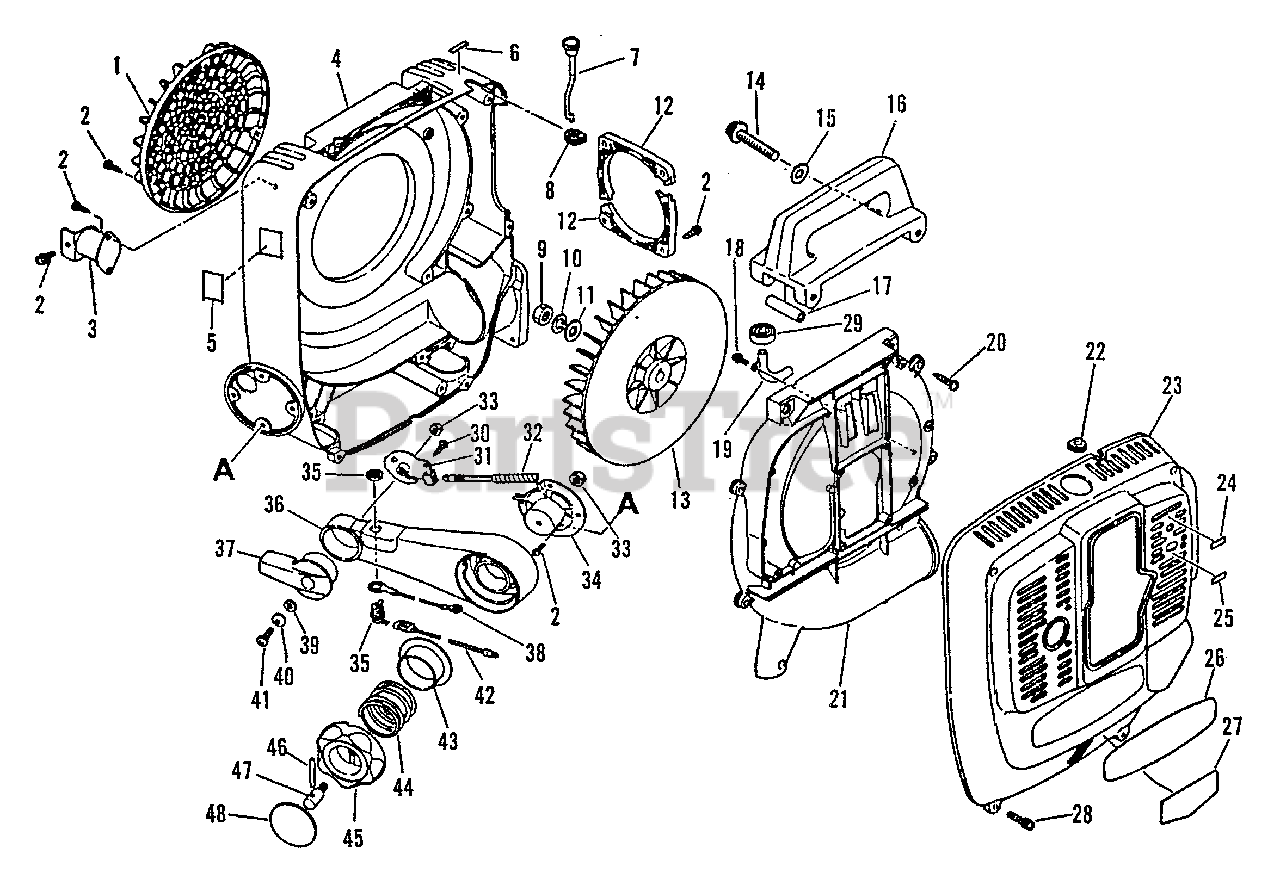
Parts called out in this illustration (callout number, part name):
1	GUARD, DEBRIS
2	SCREW - 5X14
4	COVER, FAN - INNER
5	LABEL - CAUTION
6	LABEL - CHOKE
7	ROD, CHOKE
9	NUT - 10
10	LOCKWASHER - 10
11	WASHER - 10
12	RETAINER
13	FAN
14	SCREW - 6X70
15	WASHER - 6
18	SCREW - 4X10
19	PIPE - INTAKE
20	SCREW - 5X25
21	GUARD, FAN
23	COVER, FAN - OUTER
24	LABEL - IDLE
25	LABEL - CAUTION
26	LABEL - ECHO
27	LABEL - MODEL
28	SCREW - 5X20
30	SCREW - 4X10
31	BRACKET, THROTTLE
32	WRAP, SPIRAL - 130mm
33	LOCKNUT - 6
34	PLATE
35	IGNITION SWITCH ASSY
36	ARM, THROTTLE CONTROL
37	TRIGGER, THROTTLE
38	LEAD - GROUND
39	WASHER - 6
41	SCREW - 6X20
42	LEAD - IGNITION
43	SEAT, SPRING
45	KNOB
48	LABEL
